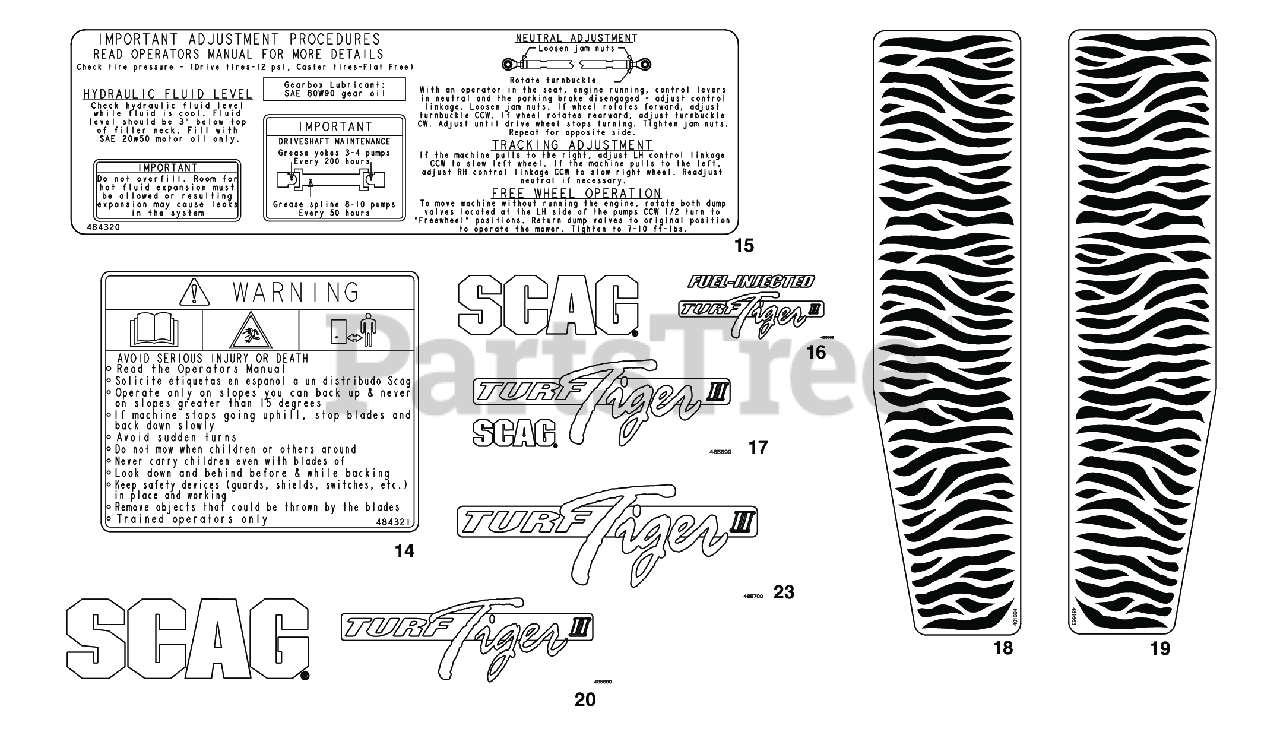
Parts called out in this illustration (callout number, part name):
14	Decal, Start/Drive Procedure
15	Decal, Checks and Adjustments
16	Decal, Hood - STTII Fuel Injected
17	Decal, Turf Tiger II
18	Decal, Stripes-RH
19	Decal, Stripes-LH
20	Decal, Hood - STTII
23	Decal, Turf Tiger II
